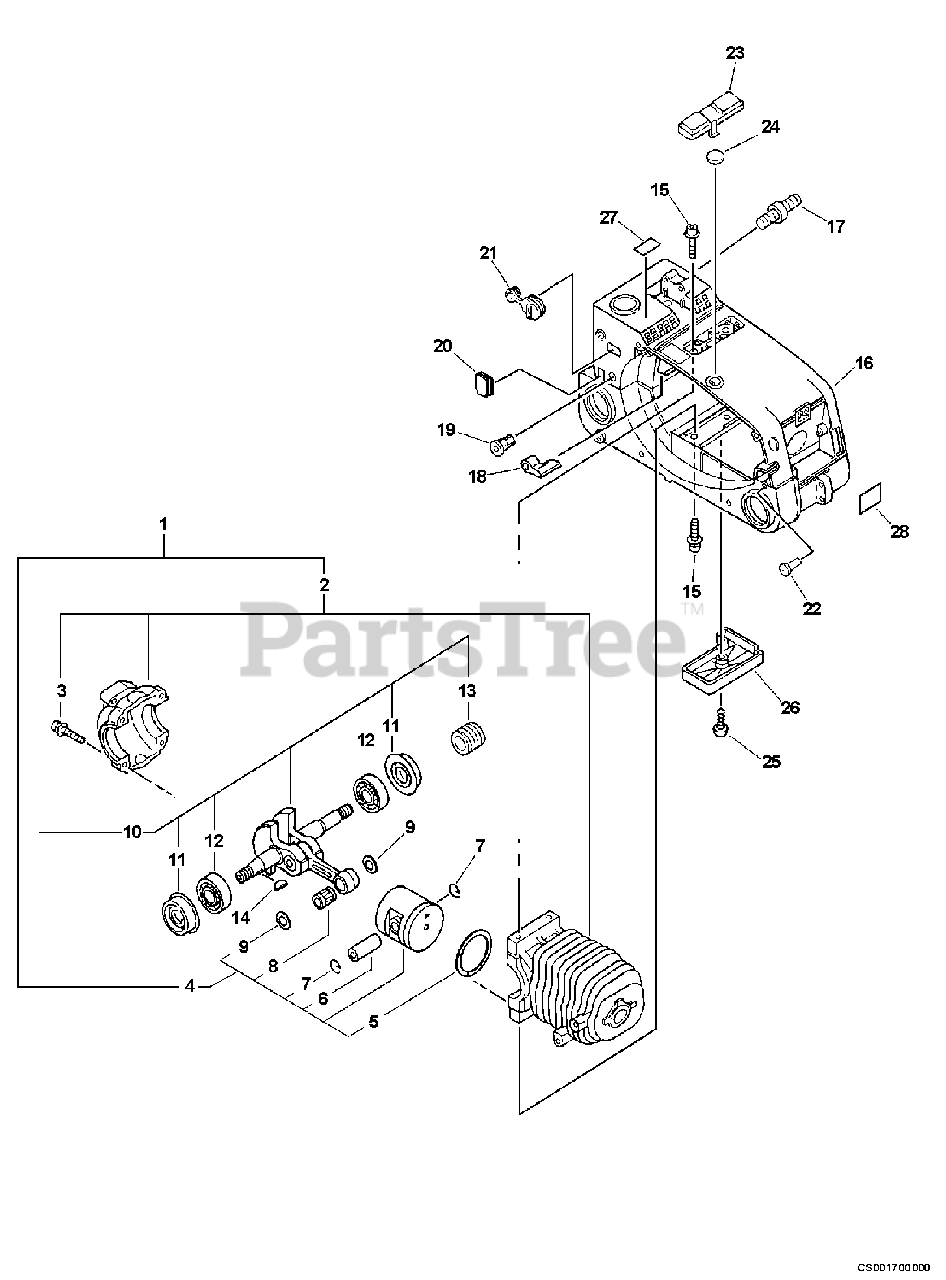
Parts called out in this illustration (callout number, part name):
1	SHORT BLOCK -- SB1052
2	CRANKCASE KIT
3	SCREW - 5X25
4	PISTON KIT
5	RING, PISTON
6	PIN, PISTON
7	RING, RETAINING
8	BEARING, NEEDLE
9	SPACER, PISTON
10	CRANKSHAFT ASSY
11	SEAL, OIL - 12
12	BEARING, BALL - 6201
13	GEAR - WORM
15	SCREW - 5X16
16	COVER, ENGINE - GRAY
17	STUD, GUIDE BAR
22	VENT, TANK
23	COVER - GRAY
25	SCREW - 4X16
26	COVER, BOTTOM - GRAY
27	LABEL - PURGE PUMP
28	LABEL - HOT SURFACE
